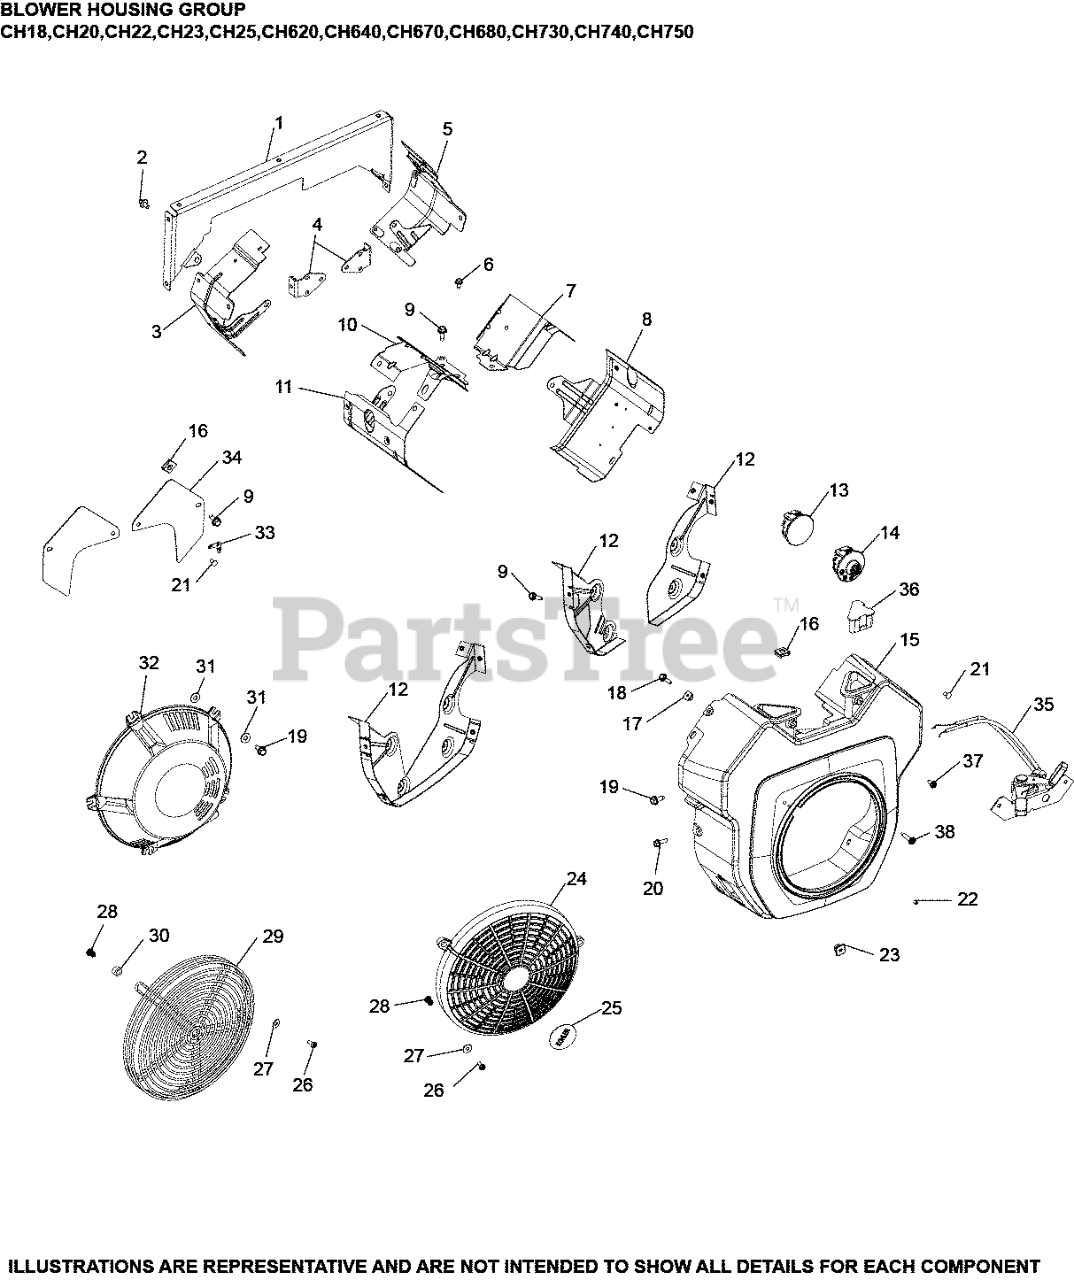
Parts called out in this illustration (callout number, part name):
6	SCREW, THREAD FORMING
7	BAFFLE, VALLEY #1 CYLINDER USE 24 063 114-S
8	KIT, CYL BAFFEL #1 SIDE
9	SCREW, THREAD FORMING
10	BAFFLE, VALLEY #2 CYLINDER
11	KIT, CYL BAFFEL #2 SIDE
12	KIT, BACKING PLATE
15	HOUSING, BLOWER
19	SCREW, THREAD FORMING
